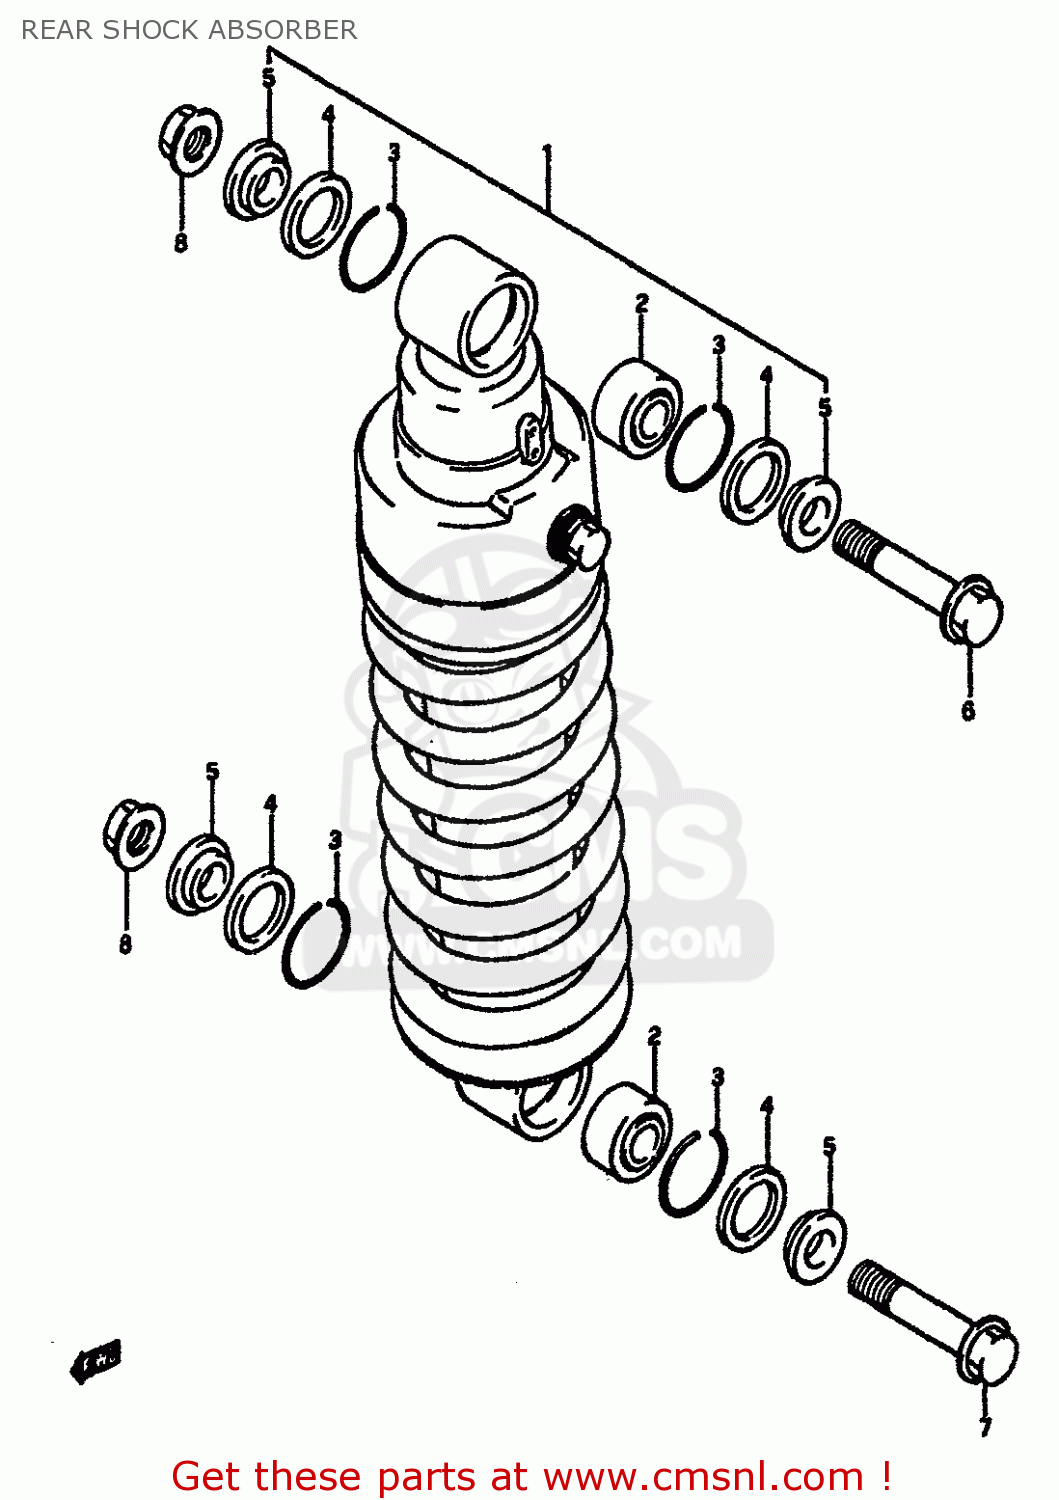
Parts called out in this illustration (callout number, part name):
1	ABSORBER ASSEMBLY,REAR SHOCK
2	BEARING,REAR SHOCK ABSORBER
3	RING
4	SEAL,DUST
5	SPACER
6	BOLT(10X54)
7	BOLT(10X52)
8	NUT
